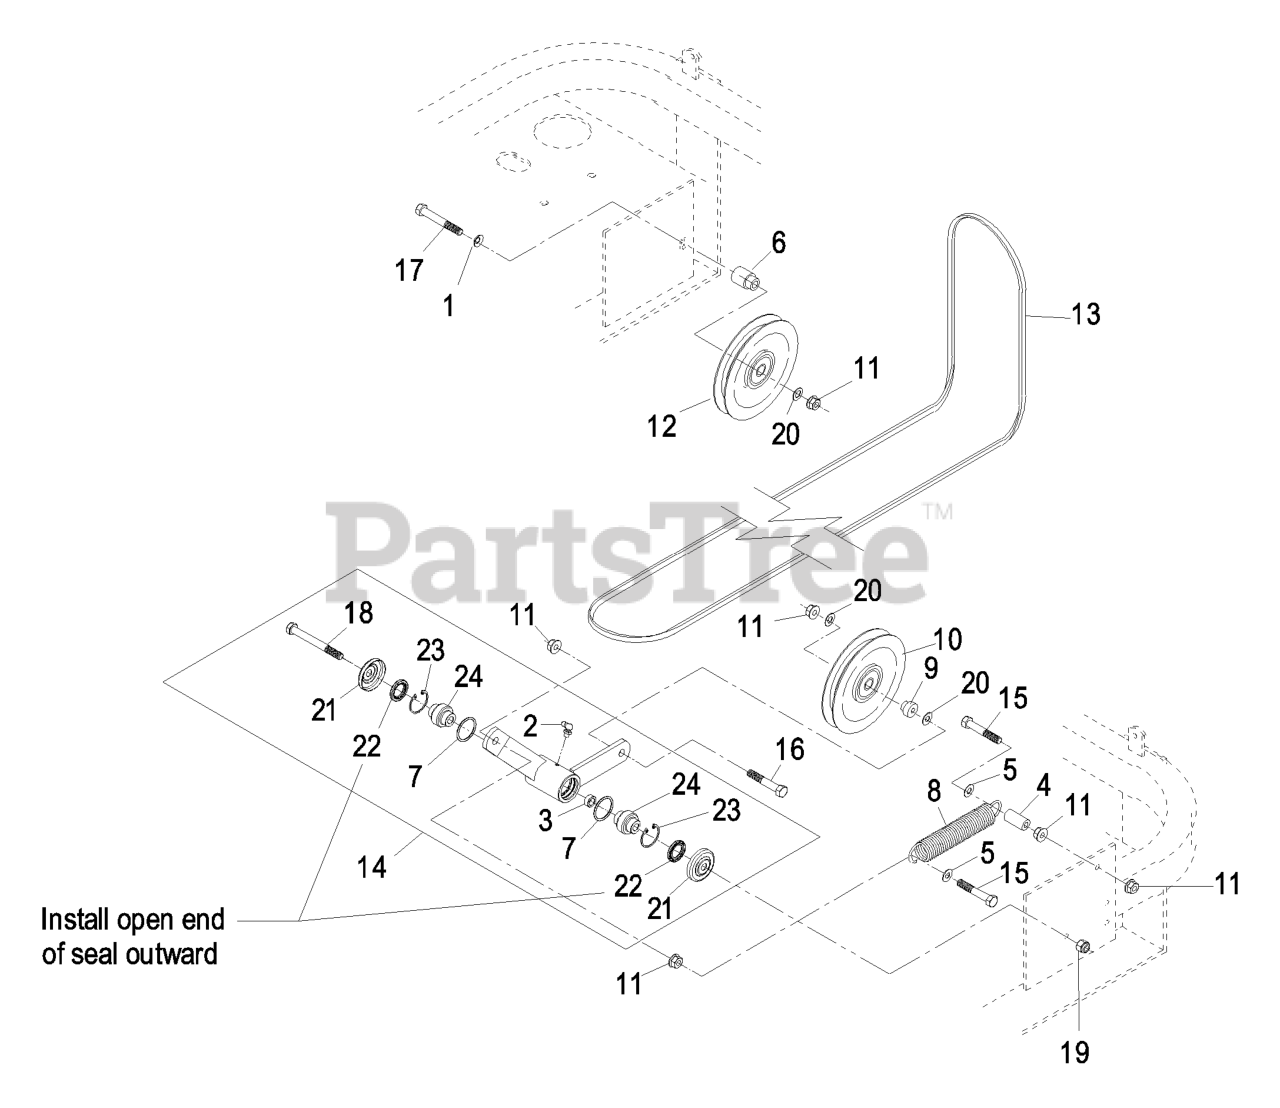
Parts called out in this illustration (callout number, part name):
1	WASHER-BELLEVILLE
2	FITTING-GREASE, 90 DEG
5	WASHER-FLAT
6	BUSHING-IDLER
8	SPRING-EXTENSION
9	BUSHING-IDLER
10	PULLEY-IDLER
11	NUT-HHF, WHIZ
12	PULLEY-IDLER
13	BELT,B 116.1"
14	KIT,MULE IDLER LZ
15	SCREW-HH
16	SCREW-HH
17	SCREW-HH
18	SCREW-HH
19	NUT-LOCK, NI
20	WASHER-FLAT
21	GUARD-TOP
22	SEAL-LIP, SINGLE
23	RING-SNAP
24	BEARING-SPHERICAL
